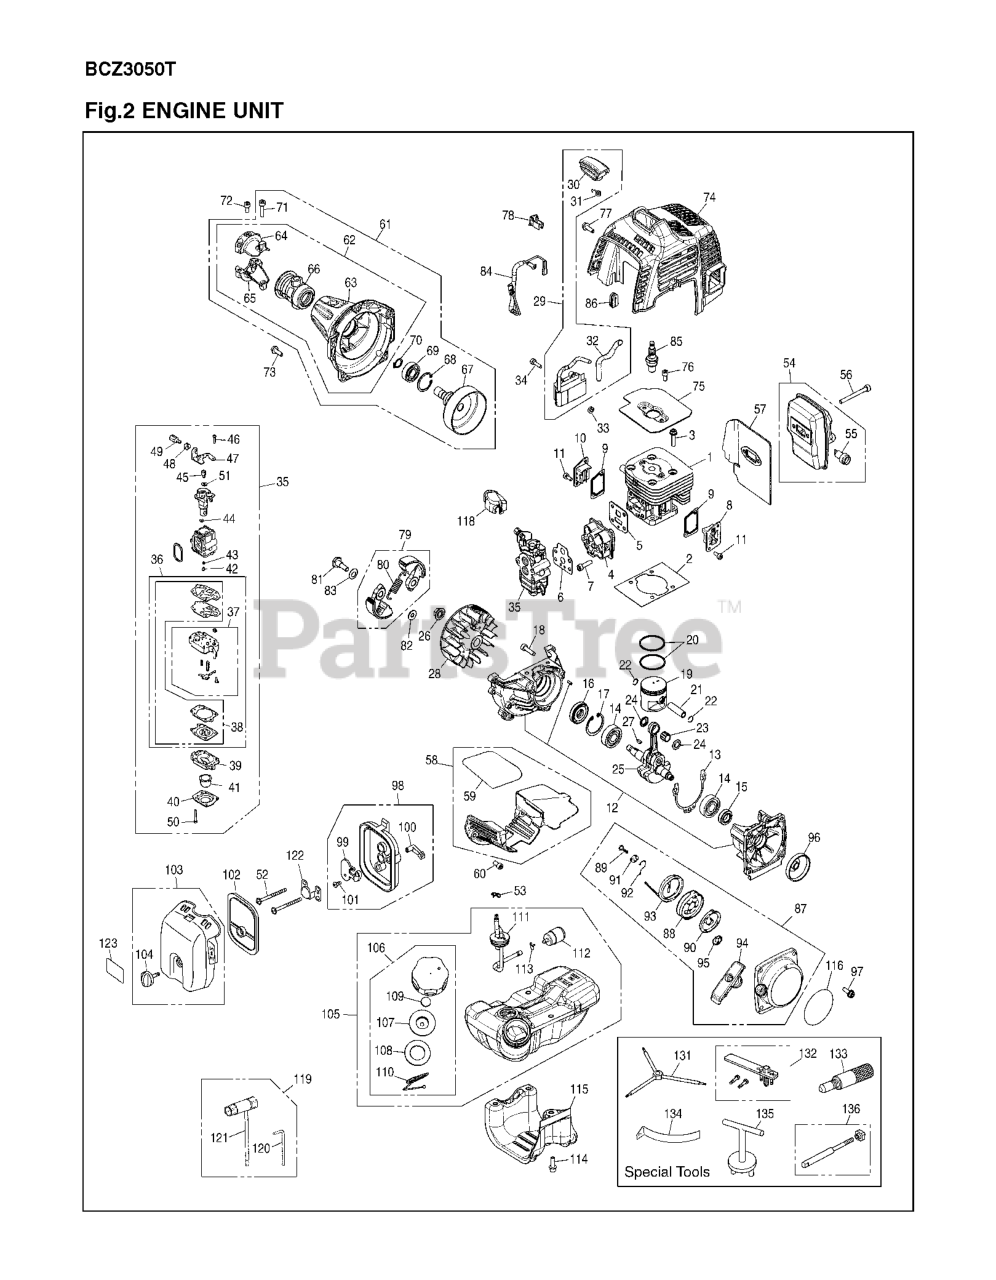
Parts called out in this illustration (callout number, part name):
1	CYLINDER
2	GASKET BASE
3	BOLT
4	INSULATOR
5	GASKET, INSULATOR
6	GASKET, CARB (RPLS T155113131)
7	BOLT, TORX
8	COVER, TRS
9	GASKET, TR
10	COVER,TRF (RPLS 848F6012D1)
11	BOLT
12	CRANKCASE-C
13	GASKET CASE
14	BEARING
20	RING
21	PIN
25	CRANKSHAFT-C
26	NUT
27	KEY
29	COIL-A
31	SPRING
33	SPACER
35	CARBURETOR ASSY
36	REBUILD KIT
37	CARBURETOR BODY
38	GASKET KIT
40	1OVER
44	RING
45	SWIVEL
46	SCREW
47	BRACKET
48	NUT
49	ADJUSTER
51	WASHER
52	CABLE THROTTLE MC9114310002
53	CLIP
54	MUFFLER ASSY
55	ARRESTER
57	GASKET
58	PLATE-A
61	HOUSING ASSY
62	HOUSING COMP.
63	HOUSING ASSY
64	DRUM (RPLS 481031120-22)
67	DRUM (RPLS 481031120-22)
69	BEARING
74	COVER, ENGINE
75	RP_PLATE
79	SHOE-C
84	CORD-COMP
85	SPARK PLUG CMR7H-10
87	RECOIL ASSY
90	SPRING, SPIRAL
91	COLLAR
92	SWING ARM
95	PLATE.STOPPER
98	CLEANER BODY ASSY
99	PLATE, CHOKE
101	SCREW
102	ELEMENT
103	COVER ASSY
104	Cleaner Knob
106	CAP A
107	HOLDER-A
111	PIPE-C
112	FILTER
113	CLIP
115	GUARD, TANK
116	LABEL, RECOIL
119	TOOL SET
131	WRENCH
132	FLYWHEEL PULLER
133	STOPPER
134	GAUGE
135	PULLER
136	ROD-A
